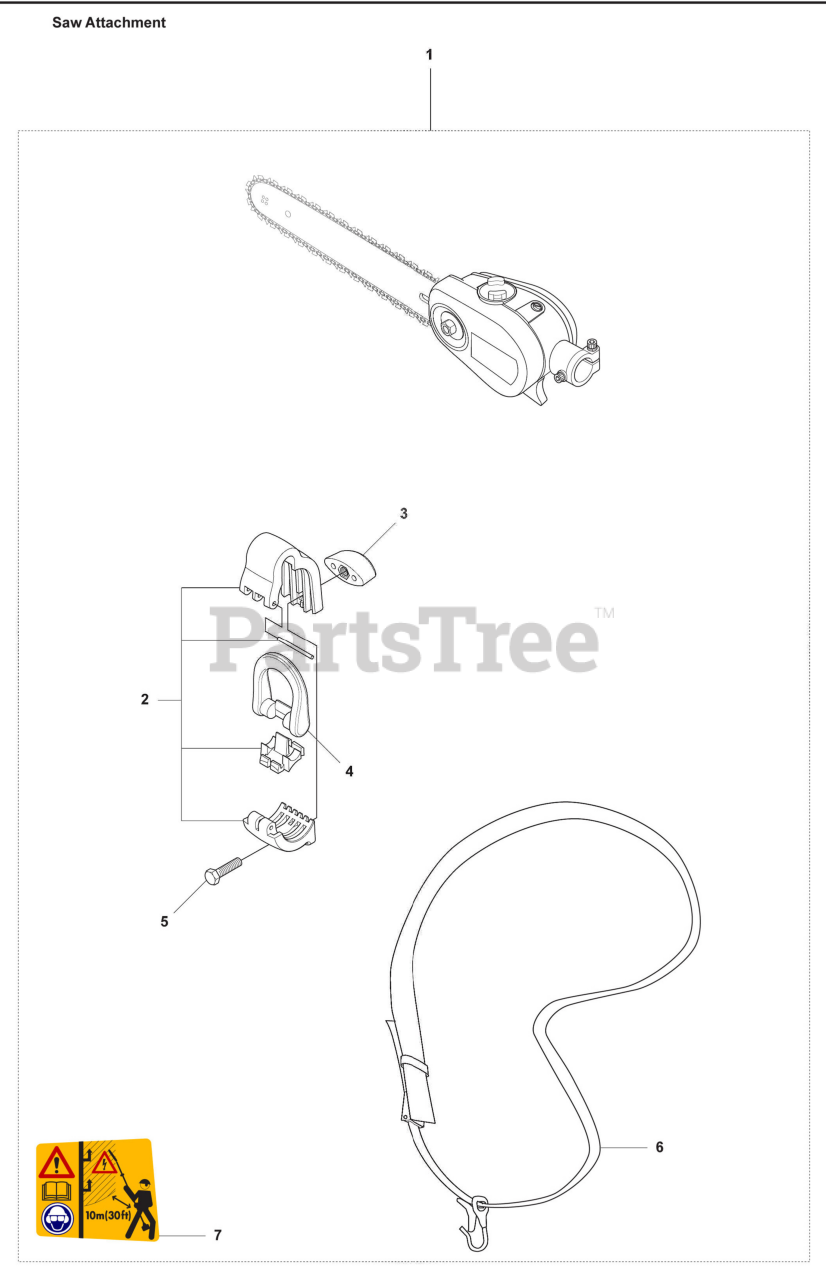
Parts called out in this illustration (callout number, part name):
1	POLE SAW HEAD 12 IN
1	Pole Saw Head W/12" Bar &
2	Hanging Bracket
5	Screw, M6S 5 X 20
6	Shoulder Strap with Sign
7	Decal
